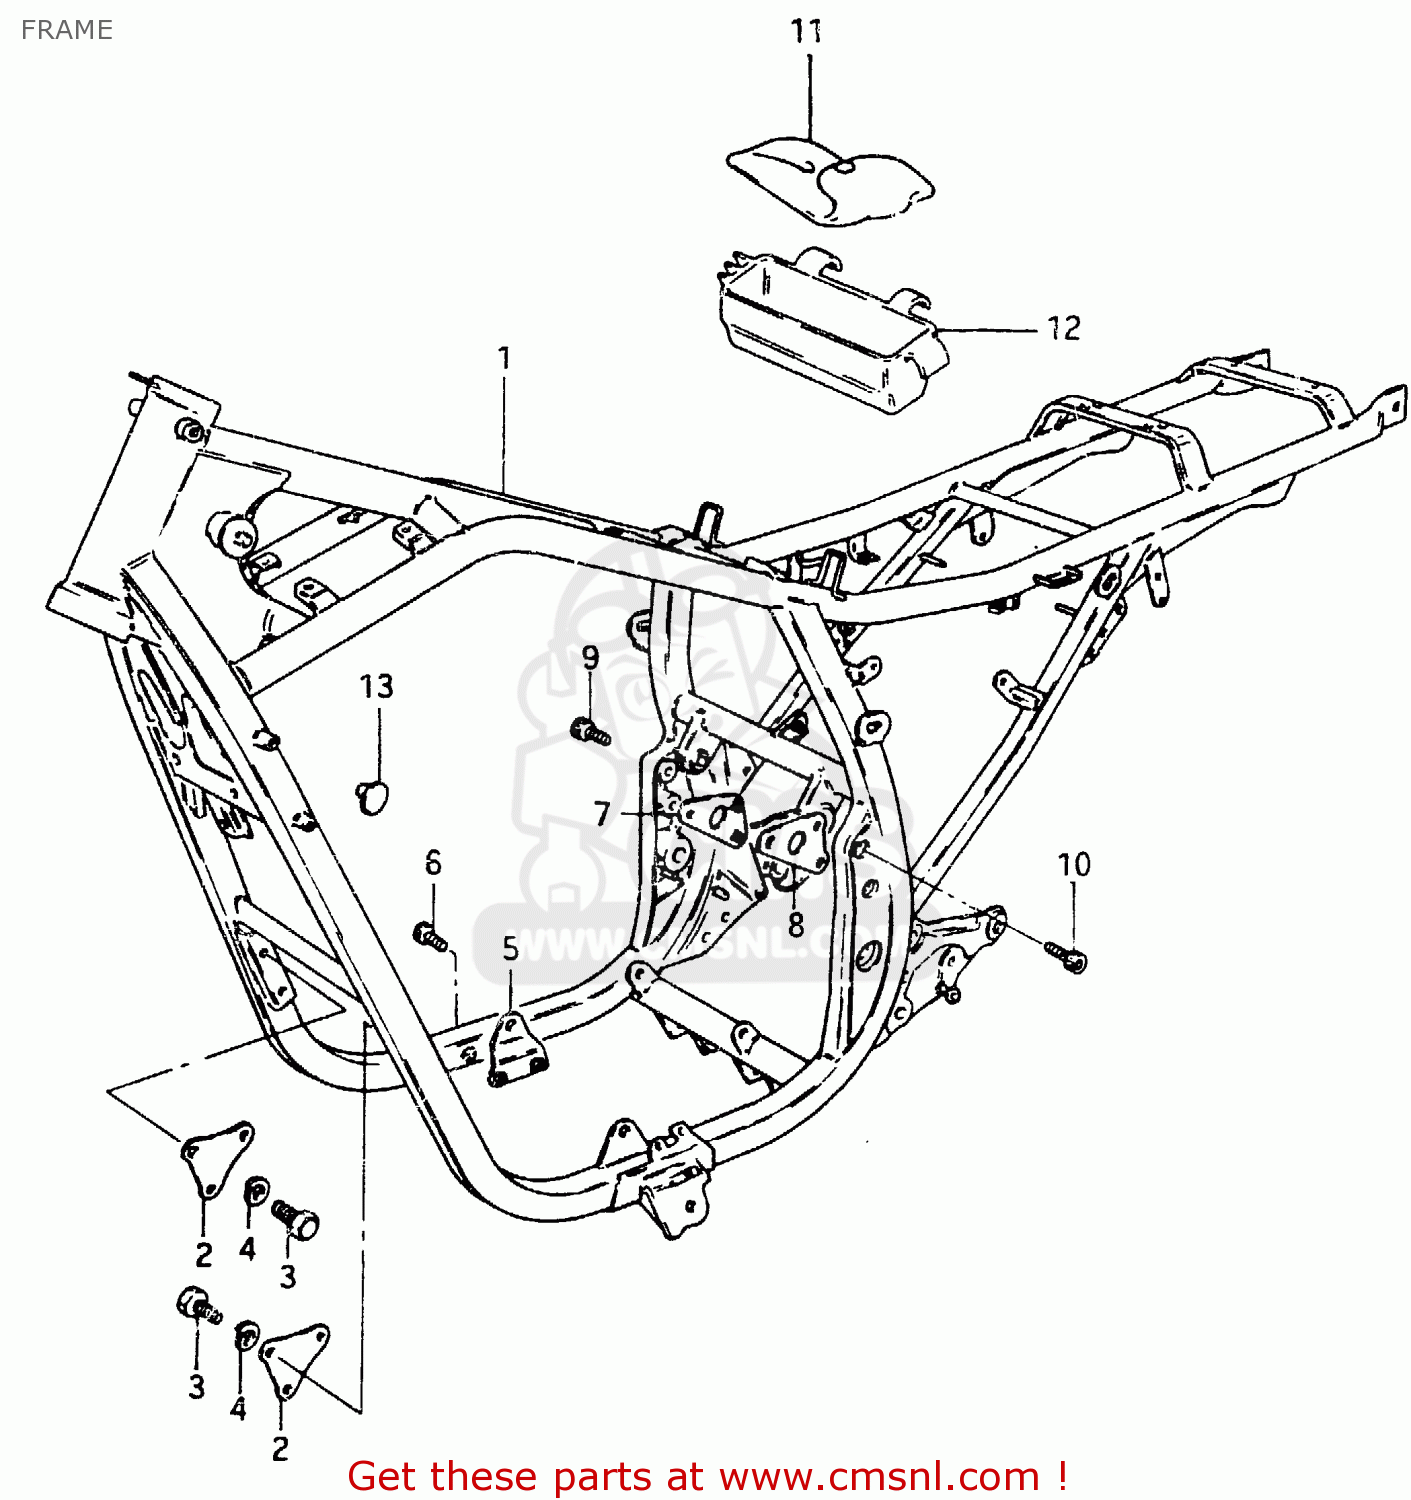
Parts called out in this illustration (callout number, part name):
1	FRAME (SILVER)
2	PLATE,ENGINE MOUNTING NO
3	BOLT
4	WASHER,LOCK,8.
5	PLATE,ENGINE MOUNTING NO
6	BOLT
7	PLATE,ENGINE MOUNTING NO
8	PLATE,ENGINE MOUNTING NO
9	BOLT 8X35
10	BOLT
11	TOOL SET
12	HOLDER,TOOL
13	PLUG
